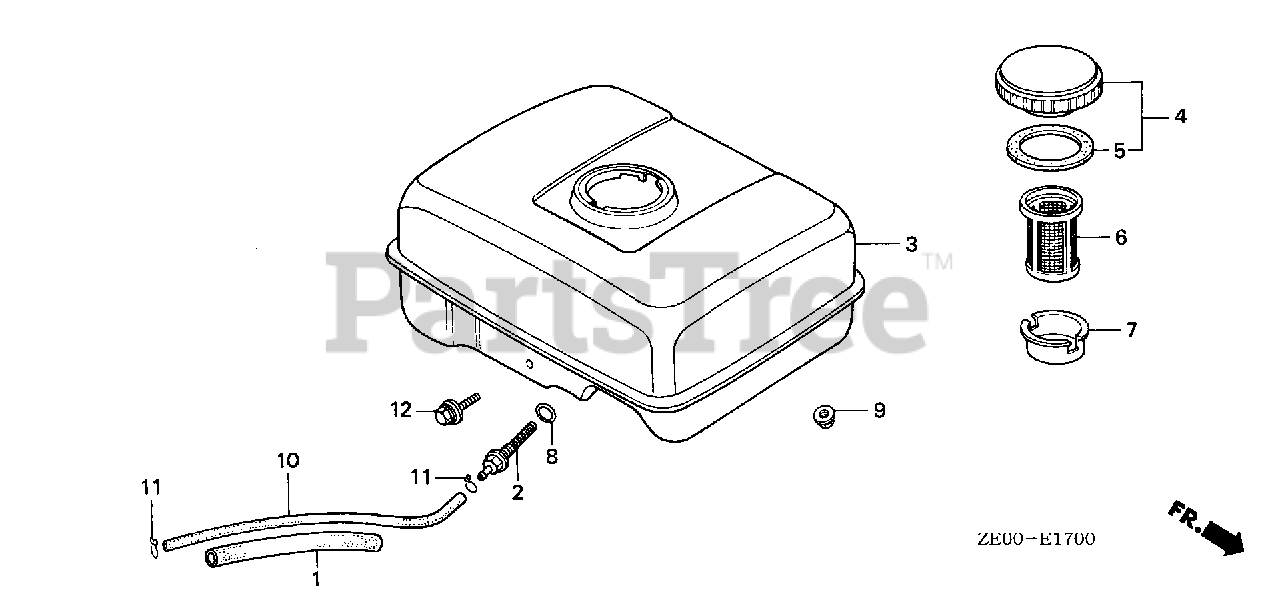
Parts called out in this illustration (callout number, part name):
1	RUBBER, SUPPORTER (107MM)
2	JOINT, FUEL TANK
3	TANK, FUEL *NH31* (MCKINLEY WHITE)
4	CAP, FUEL FILLER (BLACK)
5	GASKET, FUEL FILLER CAP (39X58X3)
6	FILTER, FUEL
7	HOLDER, FUEL FILTER
8	O-RING (13.5X1.5) (ARAI)
8	O-RING (14MM) (NOK)
9	NUT, FLANGE (6MM)
10	BULK HOSE, FUEL (4.5X3000) (4.5X140)
11	CLIP, TUBE (B8)
12	BOLT, FLANGE (6X25)
